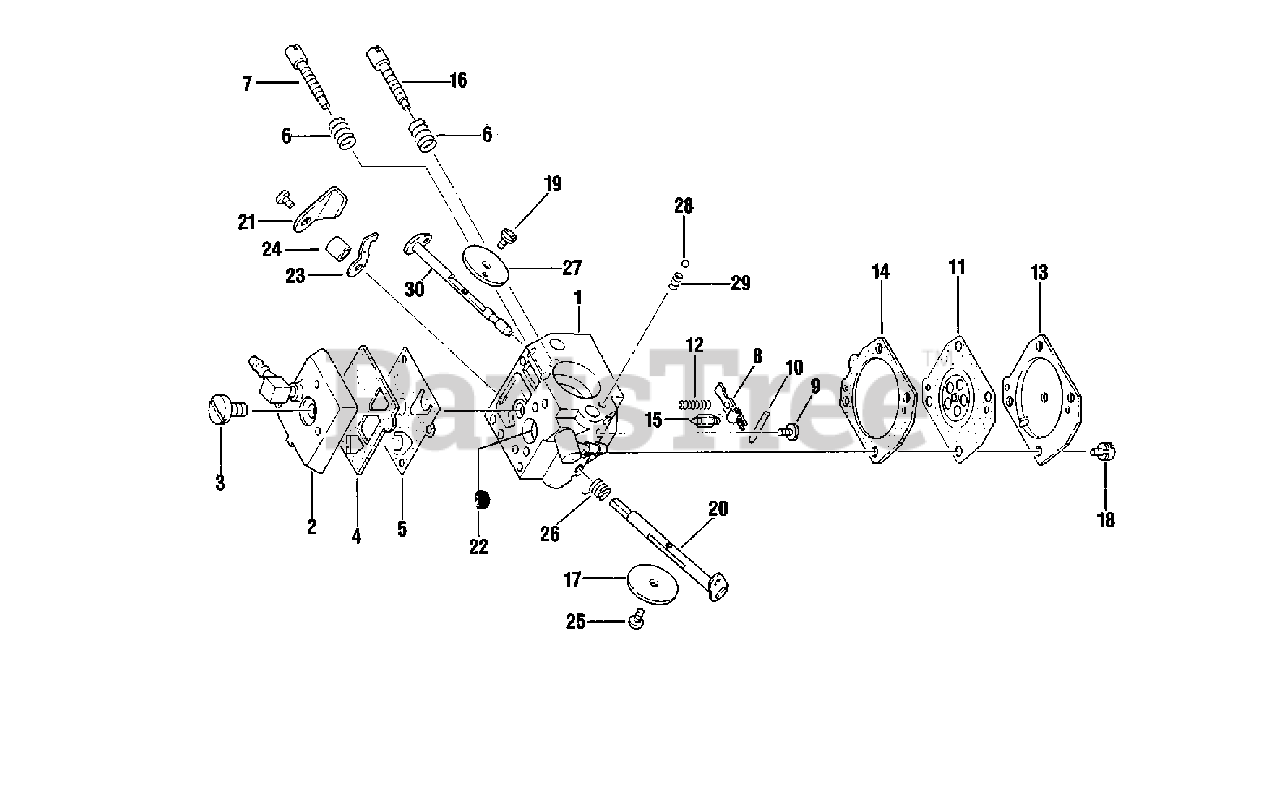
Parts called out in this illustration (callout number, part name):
1	BODY, CARBURETOR
2	COVER ASSY, PUMP
3	SCREW
4	GASKET, FUEL PUMP
4	GASKET, PUMP
5	DIAPHRAGM, FUEL PUMP
5	DIAPHRAGM, PUMP
6	SPRING, NEEDLE
7	NEEDLE, LOW SPEED
8	LEVER, METERING
9	SCREW, METERING LEVER PIN
9	SCREW
10	PIN, METERING LEVER
10	PIN
11	DIAPHRAGM, METERING
11	DIAPHRAGM ASSY
12	SPRING, METERING LEVER
12	SPRING
13	COVER, METERING DIAPHRAGM
14	GASKET, METERING DIAPHRAGM
14	GASKET, DIAPHRAGM
15	VALVE, INLET NEEDLE
15	VALVE
16	NEEDLE, HIGH SPEED
17	VALVE, THROTTLE
18	SCREW
19	SCREW
20	SHAFT, THROTTLE
21	LEVER, THROTTLE
22	SCREEN, FUEL INLET
22	STRAINER
23	STOP, THROTTLE
24	SPACER
25	SCREW ASSY
26	SPRING, THROTTLE RETURN
27	VALVE, CHOKE
28	BALL, CHOKE FRICTION
29	SPRING
30	SHAFT ASSY
